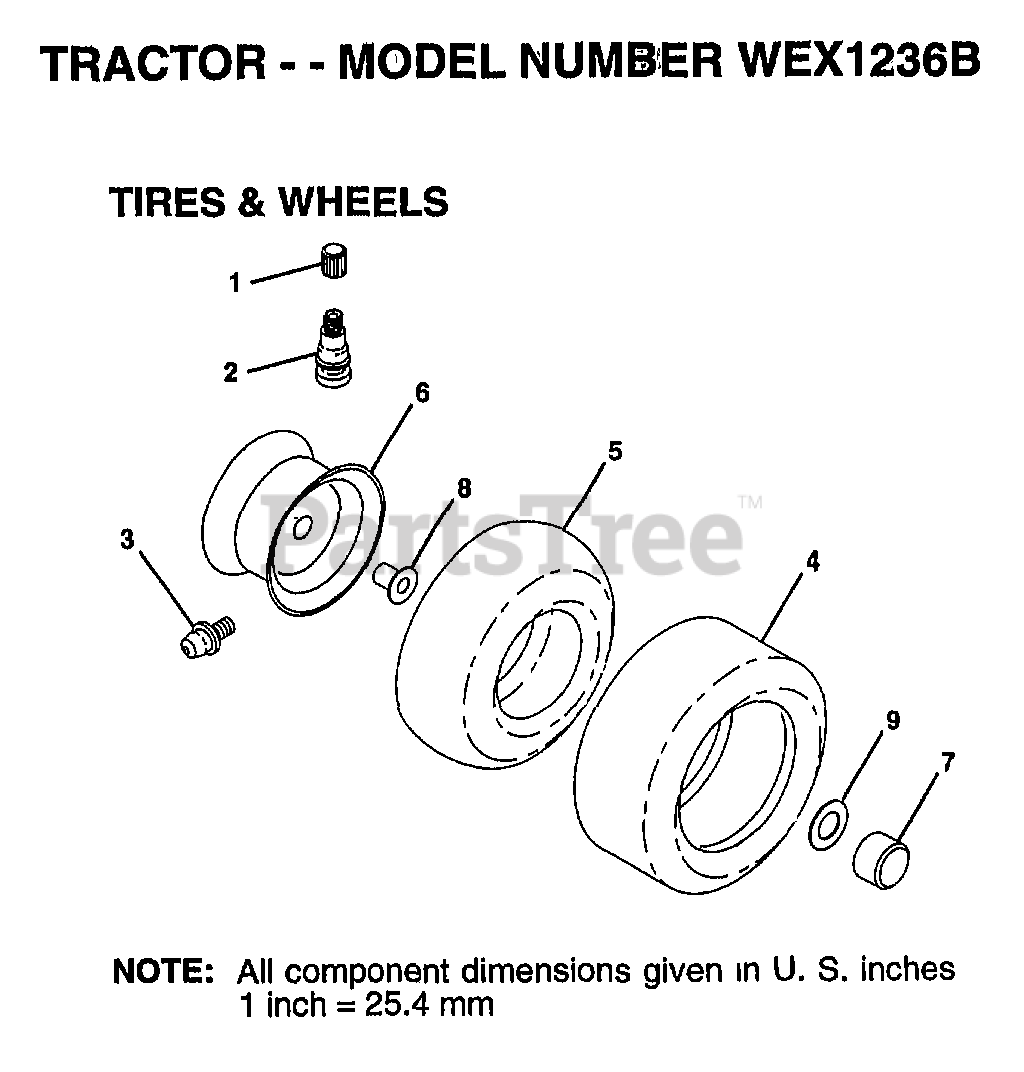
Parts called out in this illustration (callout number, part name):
1	VALVE CAP
2	VALVE STEM LT
3	FITTING LT
5	TUBE.5.3/4.5/6
5	TUBE.16X6.5/7.5-8
6	"RIM FRONT 6"""
6	"RIM ASM REAR 8"""
7	HUB CAP
8	"FLANGE, BEARING"
9	WASHER
